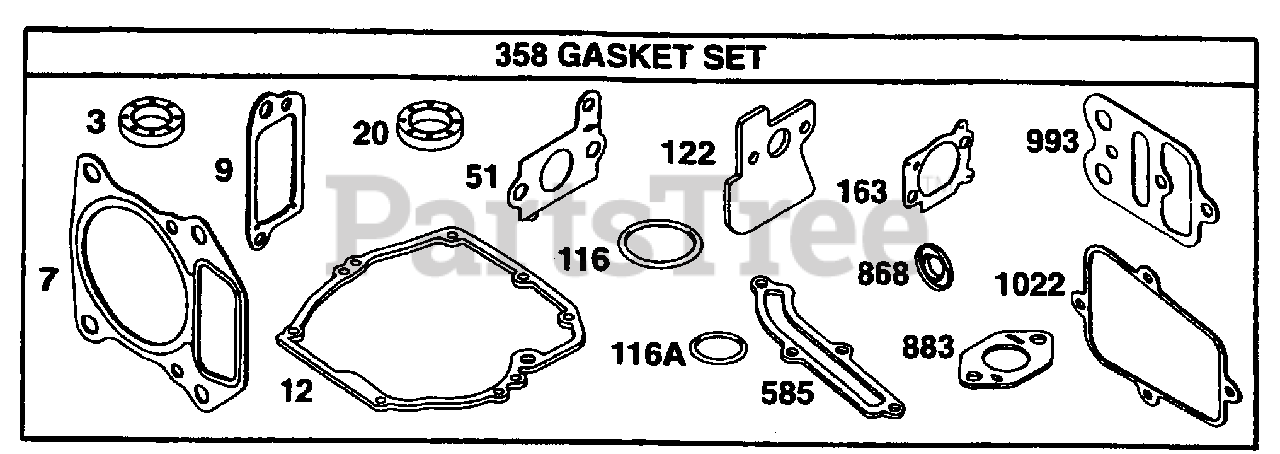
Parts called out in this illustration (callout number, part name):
3	Oil Seal
7	Cylinder Head Gasket
9	Breather Gasket
12	Crankcase Gasket
20	Oil Seal
51	Intake Gasket
116	O-Ring Seal
116A	O-Ring Seal
122	Intake Gasket
163	Air Cleaner Gasket
358	Gasket Set
585	Breather Passage Gasket
868	Valve Seal
883	Exhaust Gasket
993	Plate Gasket
1022	Rocker Cover Gasket
